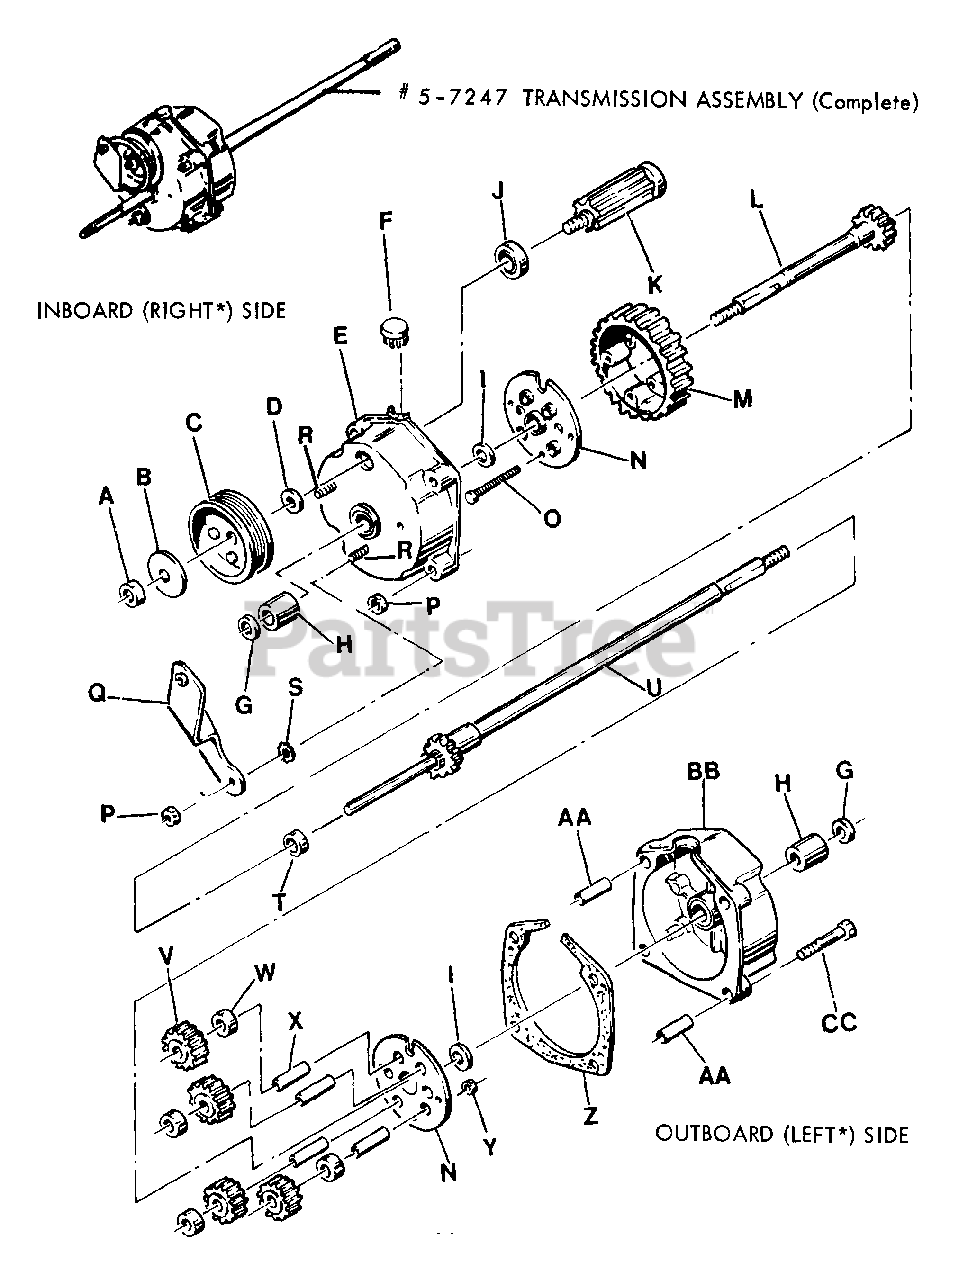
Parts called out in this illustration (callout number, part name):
A	NUT, 5/16-24 Hex Lock, GR C
B	WASHER, SPRING
C	PULLEY, POLLY V-BELT
D	WASHER, SPRING
E	HOUSING ASSEMBLY, Right
F	PLUG, HOUSING
G	SEAL
H	BEARING, TAPERED O.D.
I	WASHER, THRUST
J	BEARING, BALL
K	GEAR, INPUT-ASSEMBLY (INCLUDES ONE ITEM J)
L	AXLE, SHORT
M	GEAR, 46 TOOTH DIFFERENTIAL
N	PLATE
O	SCREW, CAP 10-32 X 1 1/2
P	NUT, LOCK 1/4-28
Q	BRACKET, DIFFERENTIAL
R	BOLT, RIB 1/4-28 x 1
S	WASHER, INT/EXT TOOTH LOCK 1/4
T	SPACER, AXLE GEAR
U	AXLE, LONG
V	GEAR, 12 TOOTH PINION
W	SPACER, PINION GEAR
X	SHAFT, PINION
Y	NUT, LOCK 10-32
Z	GASKET, HOUSING
AA	PIN, ROLL 3/8-7/16
BB	HOUSING ASSEMBLY, Left
CC	SCREW, CAP 1/4-28 X 1 3/8
